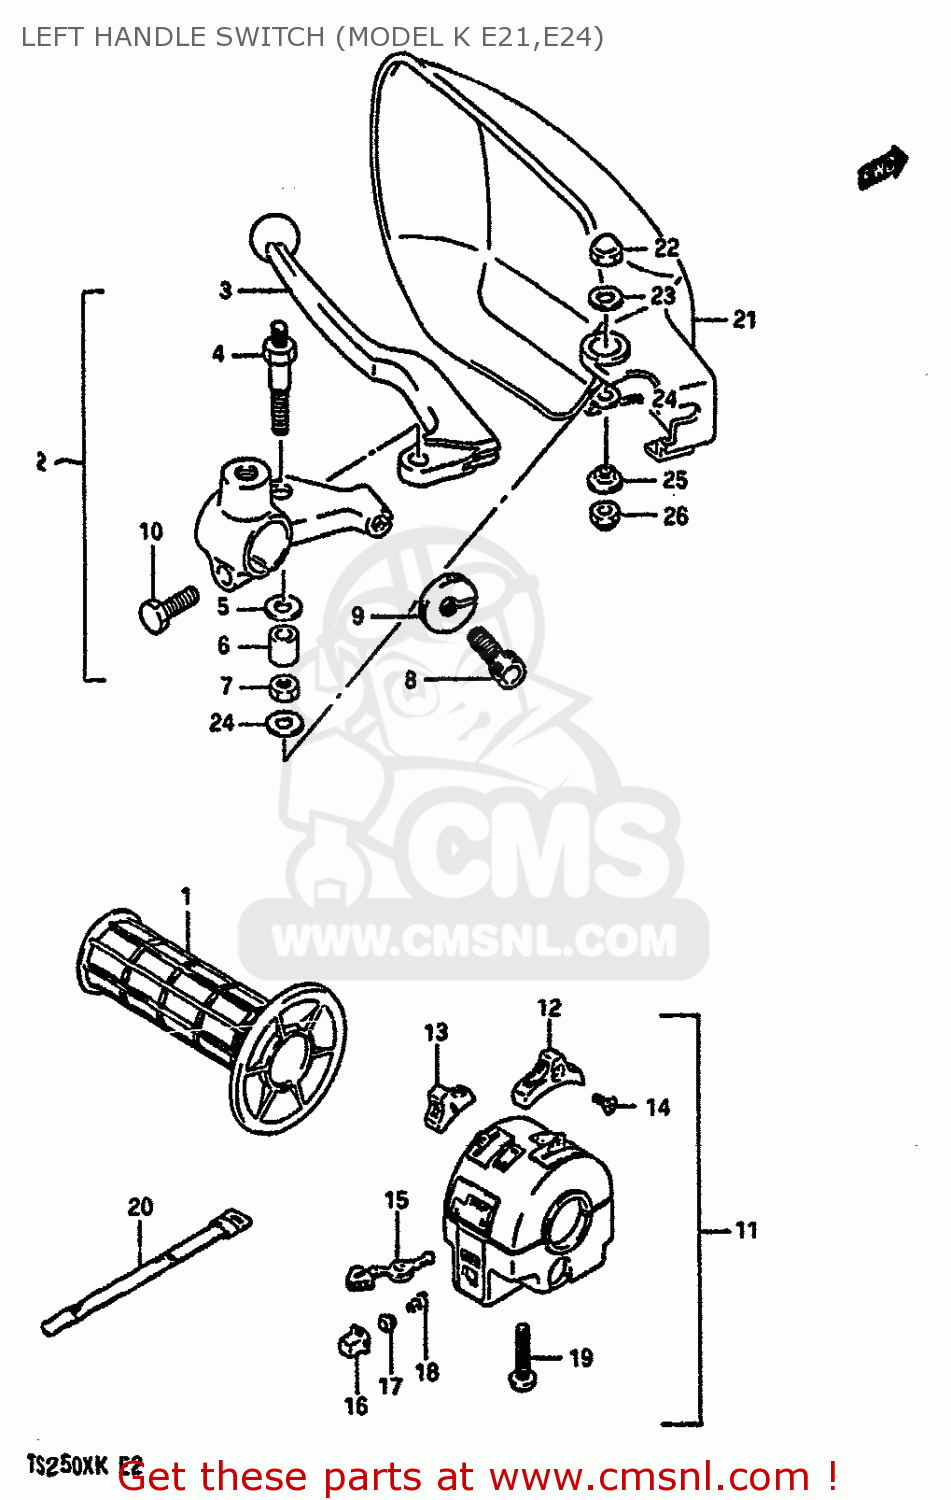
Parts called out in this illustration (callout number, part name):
1	GRIP,LEFT
2	LEVER ASSY,CLUTCH
3	LEVER,CLUTCH
4	BOLT,LEVER SET
5	WASHER,LEVER SET
6	SPACER,LEVER SET
7	NUT
8	ADJUSTER,CABLE
9	NUT,CABLE ADJUSTER LOCK
10	BOLT
11	SWITCH ASSY,HANDLE LH
12	KNOB,LIGHTING SWITCH
13	KNOB,DIMMER SWITCH
14	SCREW
15	KNOB,TURNSIGNAL
16	BUTTON,HORN
17	CONTACT
18	SPRING
19	SCREW
20	CLAMP(L:120)
21	COVER,KNUCKLE,LH (WHITE)
22	NUT 6MM
23	WASHER (6.5X20X1.6)
24	WASHER
25	WASHER
26	NUT
